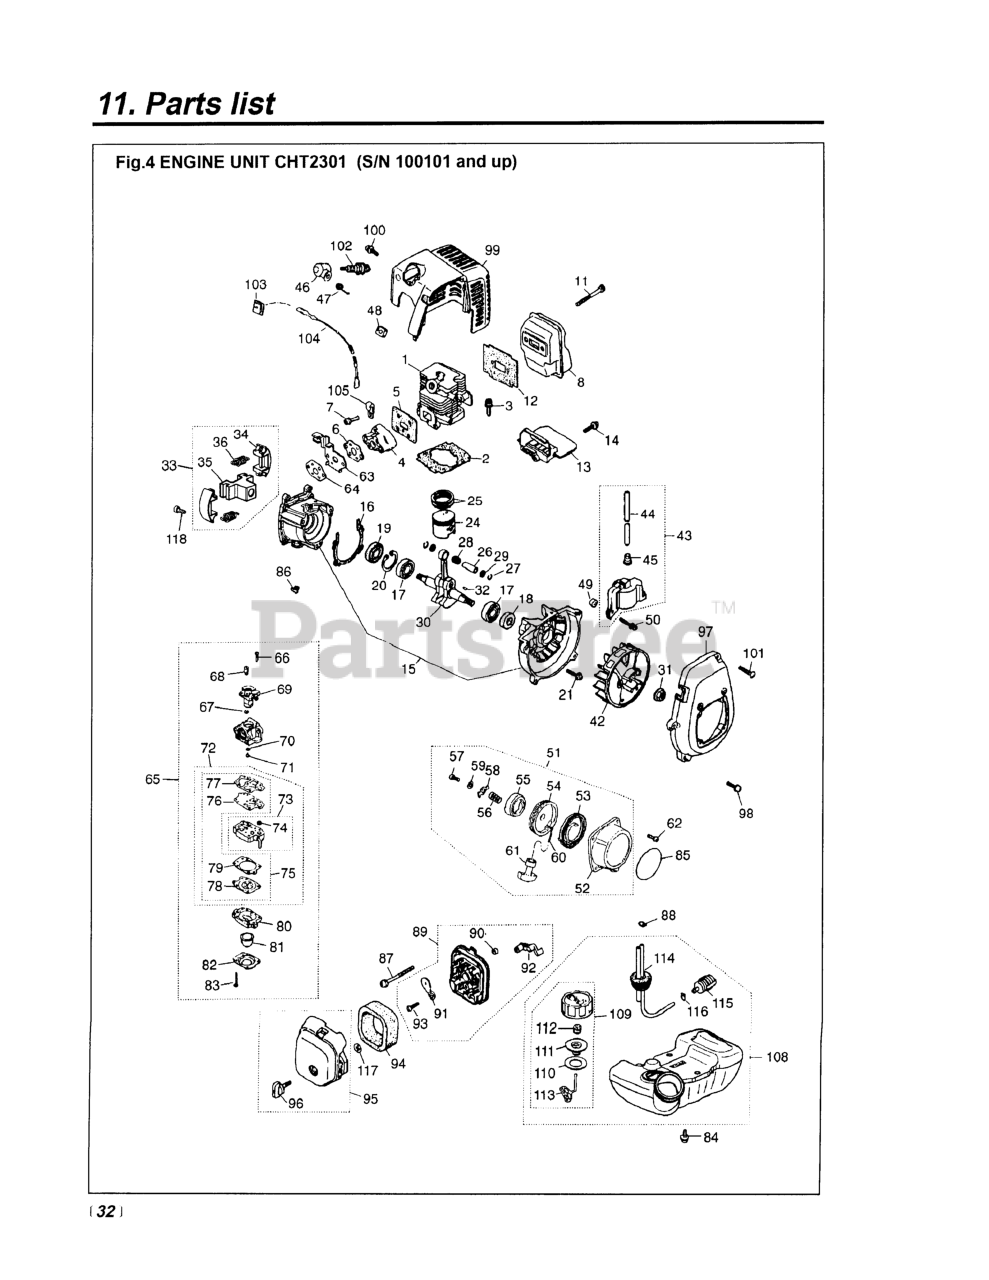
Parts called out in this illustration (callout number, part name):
1	CYLINDER
2	GASKET, BASE (RPLS -12212)
3	BOLT, M5 X 22
4	INSULATOR (REPLACES -13162)
5	GASKET (RPLS -13120)
6	GASKET (REPLACES -13130)
7	SCREW, M5X20 (RPLS.1400-75510)
8	MUFFLER
11	BOLT, M5 x 50
12	GASKET, MUFFLER (RPLS -15111)
14	SCREW, M4 X 16
15	CRANKCASE-C
16	GASKET (RPLS -21140)
17	BEARING
18	SEAL, OIL (RPLS 1100-21210)
19	SEAL, OIL (RPLS 1140-21220)
20	RING, SNAP, M28 x 1.2
21	BOLT, M5 X 30
24	PISTON (REPLACES 1140-41110)
25	RING, PISTON (RPLS 1850-41210)
26	PIN, PISTON 5x8x26
27	RING, SNAP (RPLS 1101-41320)
28	BEARING (RPLS 1140-41330)
29	WASHER
30	CRANKSHAFT (RPLS 1850-42000)
32	KEY
36	SPRING
43	COIL
45	CAP
46	CAP
47	SPRING
48	GROMMET
49	SPACER (RPLS -71260)
50	BOLT
52	CASE, RECOIL
53	SPRING
54	REEL (USE-75131)
55	5990-75141 (RPLS. 1861-75141)
56	SPRING (REPLACES -75150)
58	RETAINER
59	WASHER
60	ROPE
61	KNOB (REPLACES-75180)
62	SCREW, M4 x 12
63	BRACKET
64	GASKET (REPLACES -13130)
65	CARBURETOR
67	RING
68	SWIVEL
69	VALVE ASSY
70	RING, O
73	BODY, PUMP
74	SCREEN
76	DIAPHRAGM, PUMP
77	GASKET, PUMP
78	DIAPHRAGM
79	GASKET, DIAPHRAGM
80	BODY, PURGE
81	PUMP, PRIMING
82	COVER, PUMP
83	SCREW
85	LABEL (CHT2301)
86	CAP, CABLE END
87	SCREW, M5 x 60
88	CLIP
89	BODY ASSY.
90	SLEEVE
91	PLATE, CHOKE
92	LEVER
93	SCREW (REPLACES 50030272)
94	ELEMENT
95	COVER ASSY (RPLS -82202)
96	KNOB (RPLS -82220)
97	COVER, FAN
98	SCREW, M5X20 (RPLS.1400-75510)
100	SCREW, M5 x 12
101	SCREW, HOUSING
105	CLAMP
108	TANK-A
109	CAP ASSY (RPLS -85201)
110	PACKING
111	HOLDER (REPLACES -85230)
112	FILTER
113	STOPPER
114	PIPE COMPLETE
115	FILTER (RPLS 1850-85300)
116	CLIP (REPLACES 2841-31280)
117	CLIP
